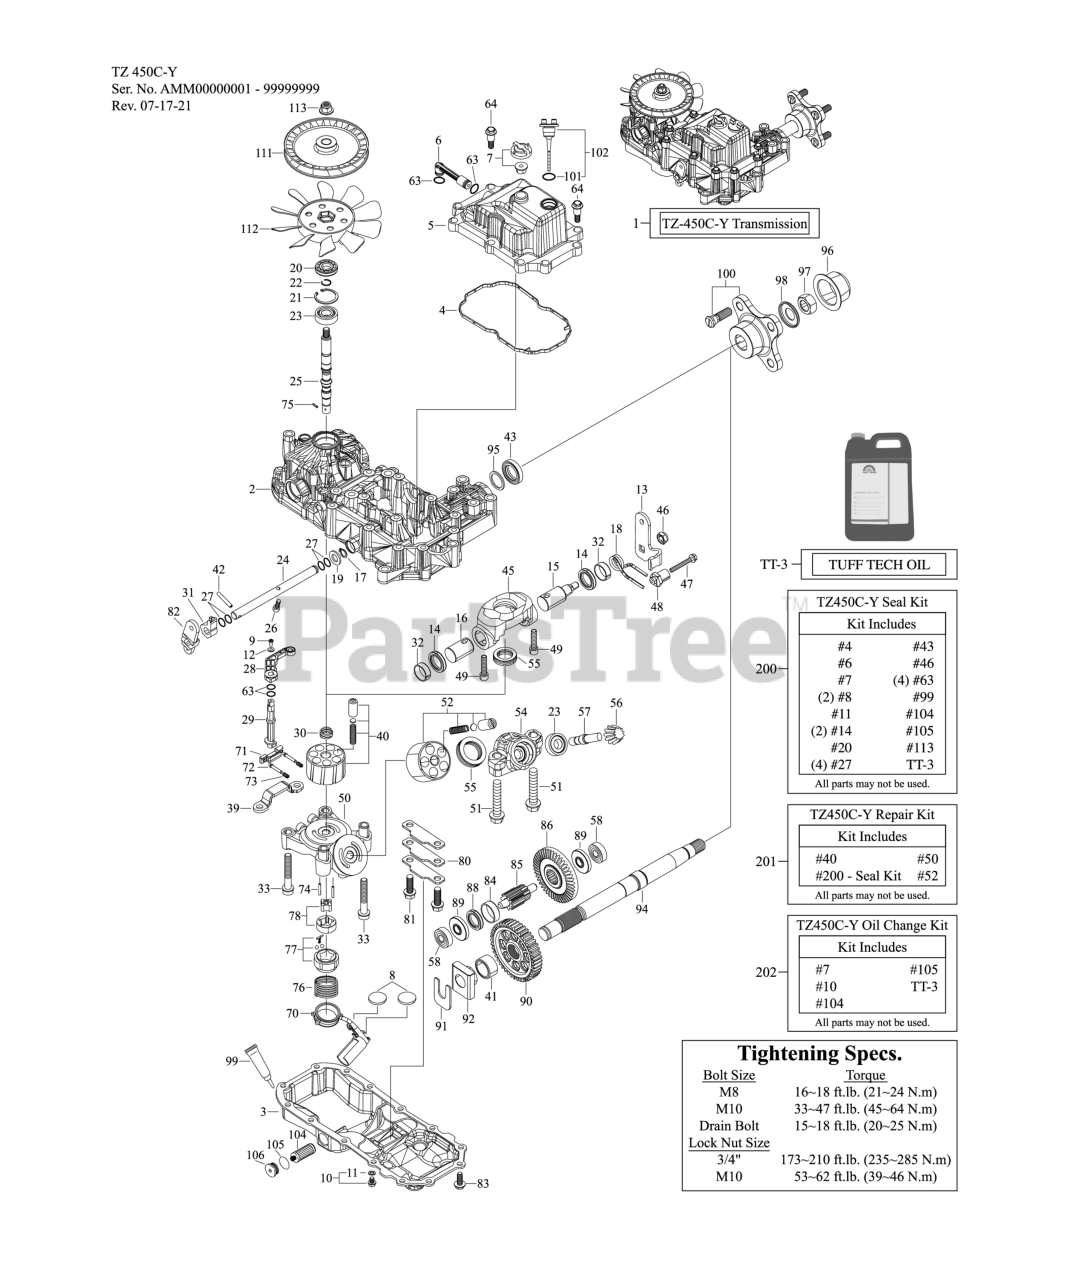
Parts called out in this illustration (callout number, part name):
1	Transaxle - Tuff Torq, RH - SZL
2	Upper Housing X
3	Lower Housing Fy
4	Square Seal
5	Top Cover A
6	Bypass Piping
7	Vent Valve
8	Magnet 28 * 3.5
9	Screw 4.0*8
10	Drain Bolt Kit
11	Washer Seal 10
12	Washer 4.5*10*1
13	Control Lever L
14	Seal, Tc253506
15	Control Shaft
16	Control Shaft Short
17	Snap Ring
18	Torsion Spring
19	Washer 12
20	Oil Seal 15*35*07
21	Snap Ring C 35
24	Brake Shaft
25	Pump Shaft C
26	Socket Bolt 6*16
27	O-Ring 1a P12
28	Bypass Lever
29	Bypass Shaft
30	Pump Spring
31	Brake Fork 20 Cr
32	Control Bush Lfb2510
33	M10 * 65 Bolt
39	Check Stopper Pfg
40	Cylinder Block Kit / Order Repair Kit
41	Bushing 25.4
42	Spring Pin 5 * 32
43	Seal Tc284008
45	Swashplate
46	Lock Nut 10
47	Bolt 6*45
49	Bolt 8 * 35
50	Centercase Cp / Order Repair Kit
51	Bolt 12*65
52	Cylinder Block Kit(Motor / Order Repair Kit
54	Motor Housing
55	Thrust Bearing
56	Motor Gear S
57	Motor Shaft
58	Bearing 6201 Cn
63	0-Ring 1a P10a
64	Tapping Bolt 8*30
70	Bracket Assy Fts
71	Bypass Guide
72	Bypass Pin
73	Bypass Spring
74	Pin 3.0 * 18
75	Pin 2.5* 9.8
76	Charge Spring
77	Pump Case
78	Rotor Set
80	Final Plate
81	Bolt 10 * 30
82	Brake Arm
83	Tapping Screw 8 * 20
84	Final Pinion Collar
85	Final Pinion Shaft
86	Reduction Gear S
88	Reduction Collar
89	Reduction Collar
90	Final Gear Sv
92	Bushing 25.4
94	Axle Shaft T
96	Nut Cap
97	Lock Nut 3/4-16
98	Flange Spacer
100	Flange Assy.
101	O-Ring 1a P16
102	Dipstick Assy.
104	Filter
105	O-Ring 1a 24040
106	Cap 40
111	Pulley,5.5
112	Fan
113	Lock Nut 10
200	Seal Kit Tz-450
201	Repair Kit Tz-450 C
202	Tz 450 Oil Change Kit
TT-3	Tuff Tech Oil (3 Liter Bottle)
